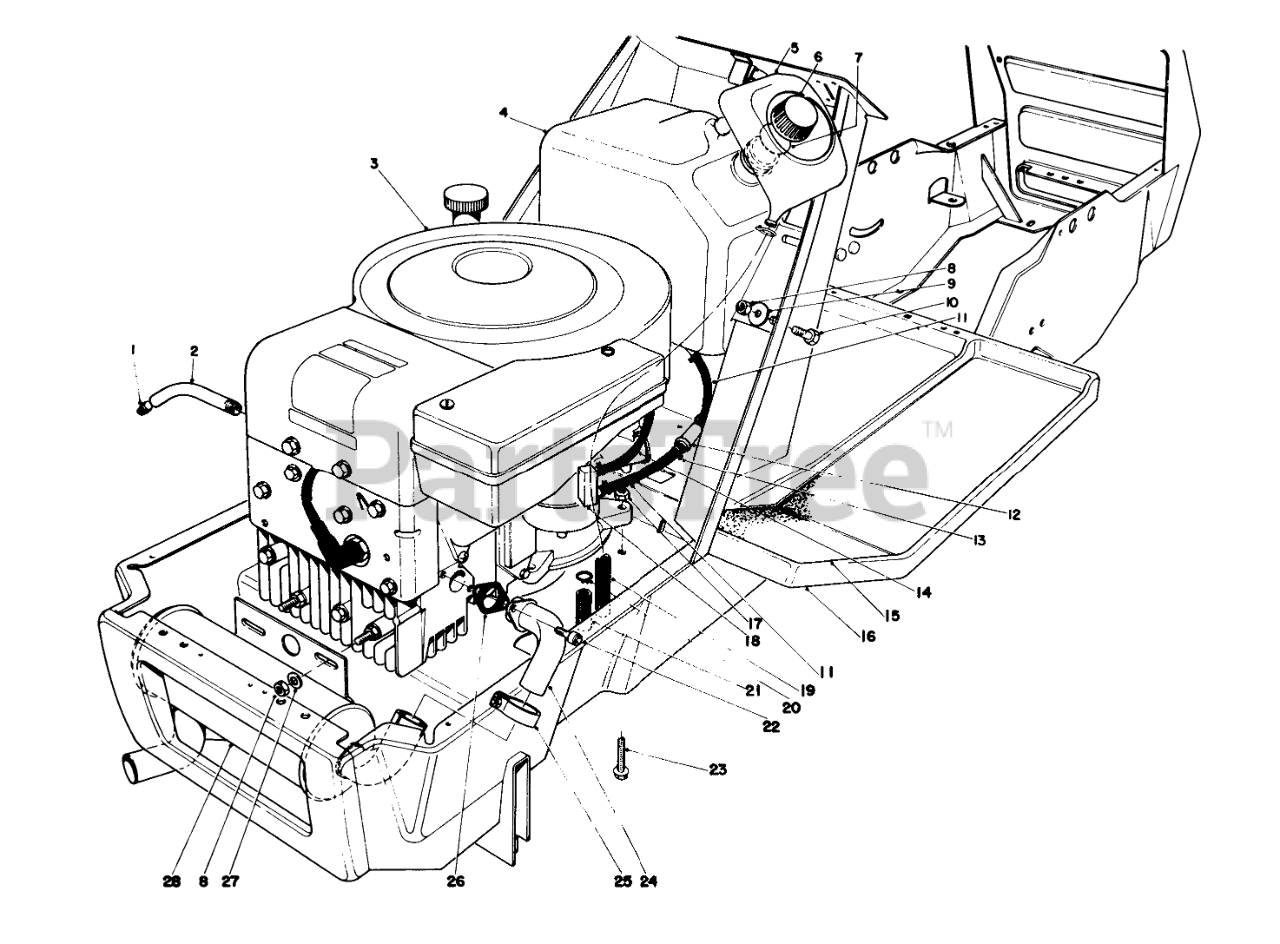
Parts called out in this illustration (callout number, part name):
1	PLUG-PIPE, SQH
2	OIL DRAIN TUBE
3	Engine
4	Gas Tank (Incl. Ref. #5)
5	Funnel Overflow
6	Gas Cap (Incl. Ref. #7)
7	Gasket Gas Cap
8	NUT-LOCK, CONE
9	Washer
10	SCREW-HH
11	GAS HOSE
12	Fuel Filter
13	Clamp
14	Gas Return Hose
15	LH FOOT TREAD
16	Frame
17	NUT-LOCK, CONE
18	Fitting Carburetor
19	Hose Funnel
20	HOSE CLAMP
21	Hose Carburetor Drain
22	SCREW-HSH
23	SCREW-HH
24	10 HP EXHAUST PIPE WA
25	MUFFLER CLAMP
26	Gasket Exhaust
27	WASHER-PLAIN
28	EXHAUST MUFFLER 10 HP
